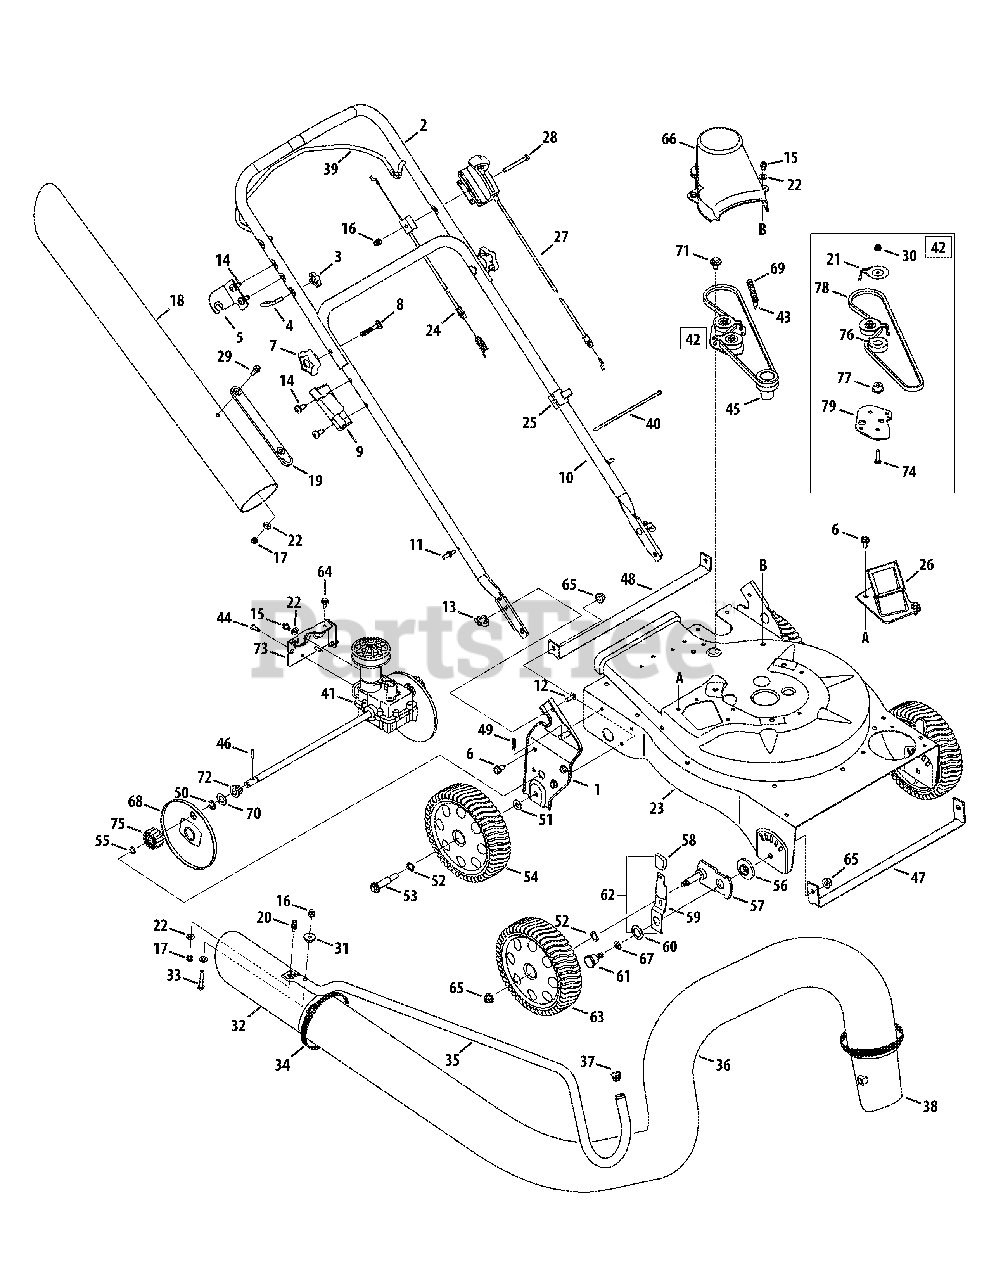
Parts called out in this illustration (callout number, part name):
1	Handle Bracket Ass’y RH
2	Upper Handle
5	Upper Handle Bracket
6	Hex Cap Screw, 5/16-12 x.750
7	Handle Knob, 5/16-18
8	Carriage Bolt
9	Nozzle Handle Clip
12	Carriage Screw, 1/4-20 x.75
13	Wing Nut, 1/4-20
14	TT Screw, 5/16-18 x .750
15	Screw, 1/4-20 x .500
16	Cap Lock Nut, 1/4-20
17	Hex Lock Nut, 1/4-20
18	Hose Extension
19	Chute Strap
21	Belt Keeper
22	Flat Washer.271 ID x.630 OD
23	Upper Flail Housing
24	Drive Control Cable
25	Cable Guide
26	Chipper Chute Assembly
27	Speed Control Cable
28	Hex Screw, 1/4-20 x 2.50
29	Screw, 1/4-20 x .75
30	Flange Lock Nut, 1/4-20
32	Hose Nozzle
33	Hex Cap Screw, 1/4-20 x 2.625
34	Adjustment Clamp
36	Vacuum Hose
37	Handle Plug
38	Hose Adapter
39	Drive Control
40	Cable Tie
41	Transmission Assembly
42	Idler Assembly (Incl. Ref.# 74-80)
43	Shoulder Screw, #12-24 x .30 x .46
44	Screw, #12-16 x .750
45	Impeller Hub
46	Dowel Pin
47	Front Wheel Support Brace
48	Rear Wheel Support Brace
49	Cotter Pin
51	Flat Washer, .406 x .875 x .105
52	Wave Washer, .531 ID x.781 OD
53	Shoulder Screw, 3/8-16
54	Wheel, 8 x 2.125
55	Snap Ring
56	Height Adjustment Bearing
57	Pivot Arm Assembly
58	Height Adjustment Knob
59	Spring Lever
60	Bell Washer, .760 ID x.25 OD
61	Shoulder Screw, .750 x.500
62	Height Lever Assembly (Incl. Ref.# 58-59)
63	Wheel 8 x 2
64	Screw, 1/4-20 x .625
65	Flange Lock Nut, 3/8-16
66	Belt Cover
67	Thrust Washer, .375 ID x.70 OD
68	Wheel Cover
69	Extension Spring, .375 x 2.95
70	Flat Wash, .508ID x1.00OD x.020
71	Shoulder Screw, .560 x.165
72	Drive Axle Bushing
73	Transmission Mounting Bracket
74	Screw, 1/4-20 x 1.00
75	Spur Gear - RH
76	Ball Bearing
77	Flange Spacer,.260 x.659 x.517
78	Belt, 3/8 x 32.5
79	Idler Bracket
